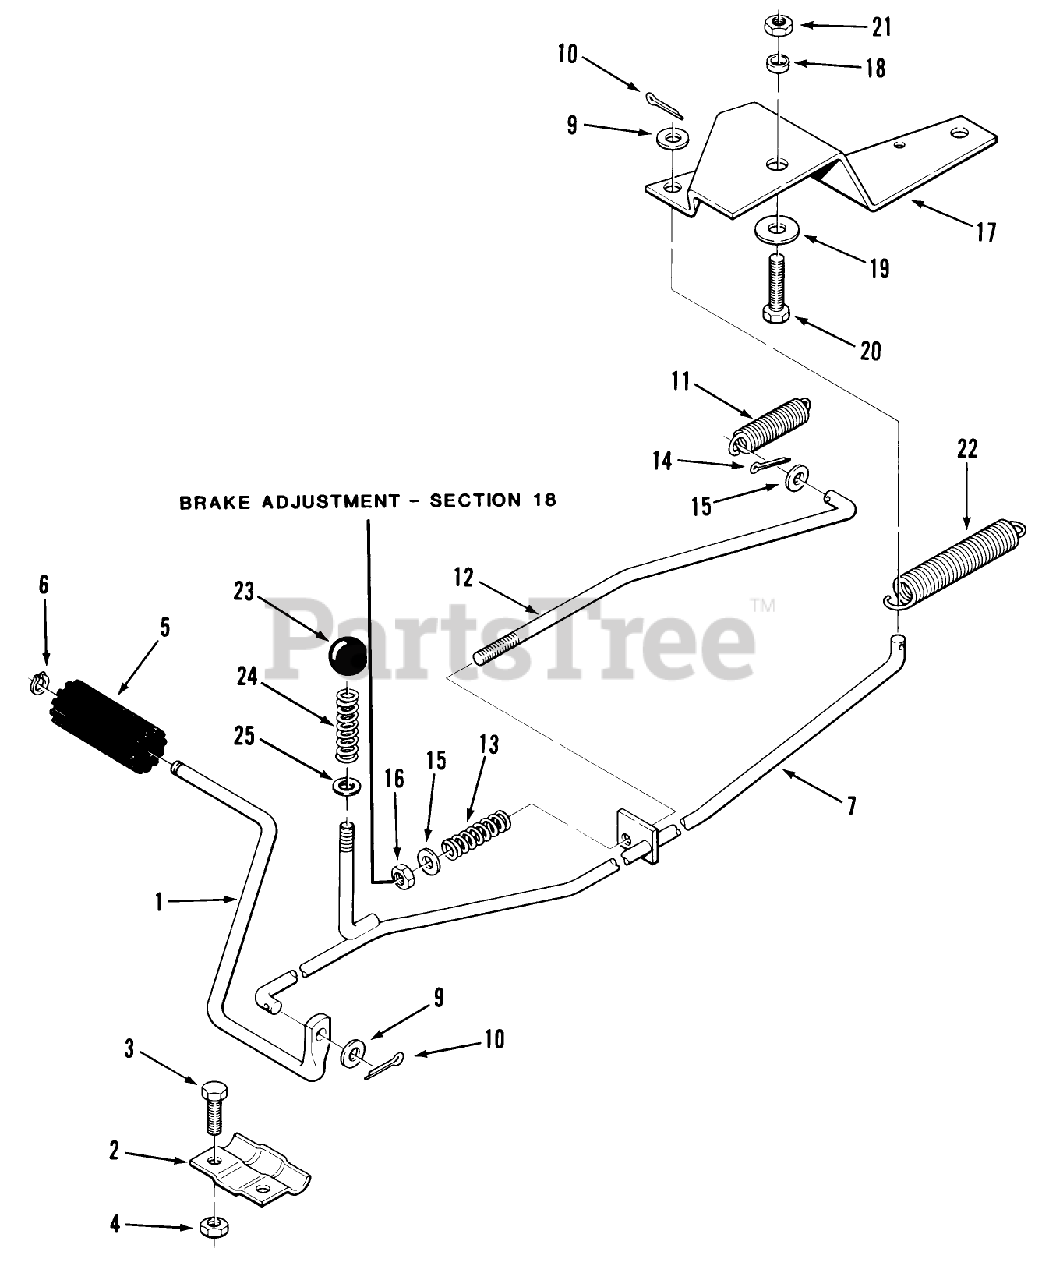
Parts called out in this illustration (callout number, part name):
2	SPINDAL SUPPORT *R
11	SPRING-EXTENSION
18	SPACER
19	WASHER
22	SPRING EXTENSION
24	SPRING
25	WASHER
